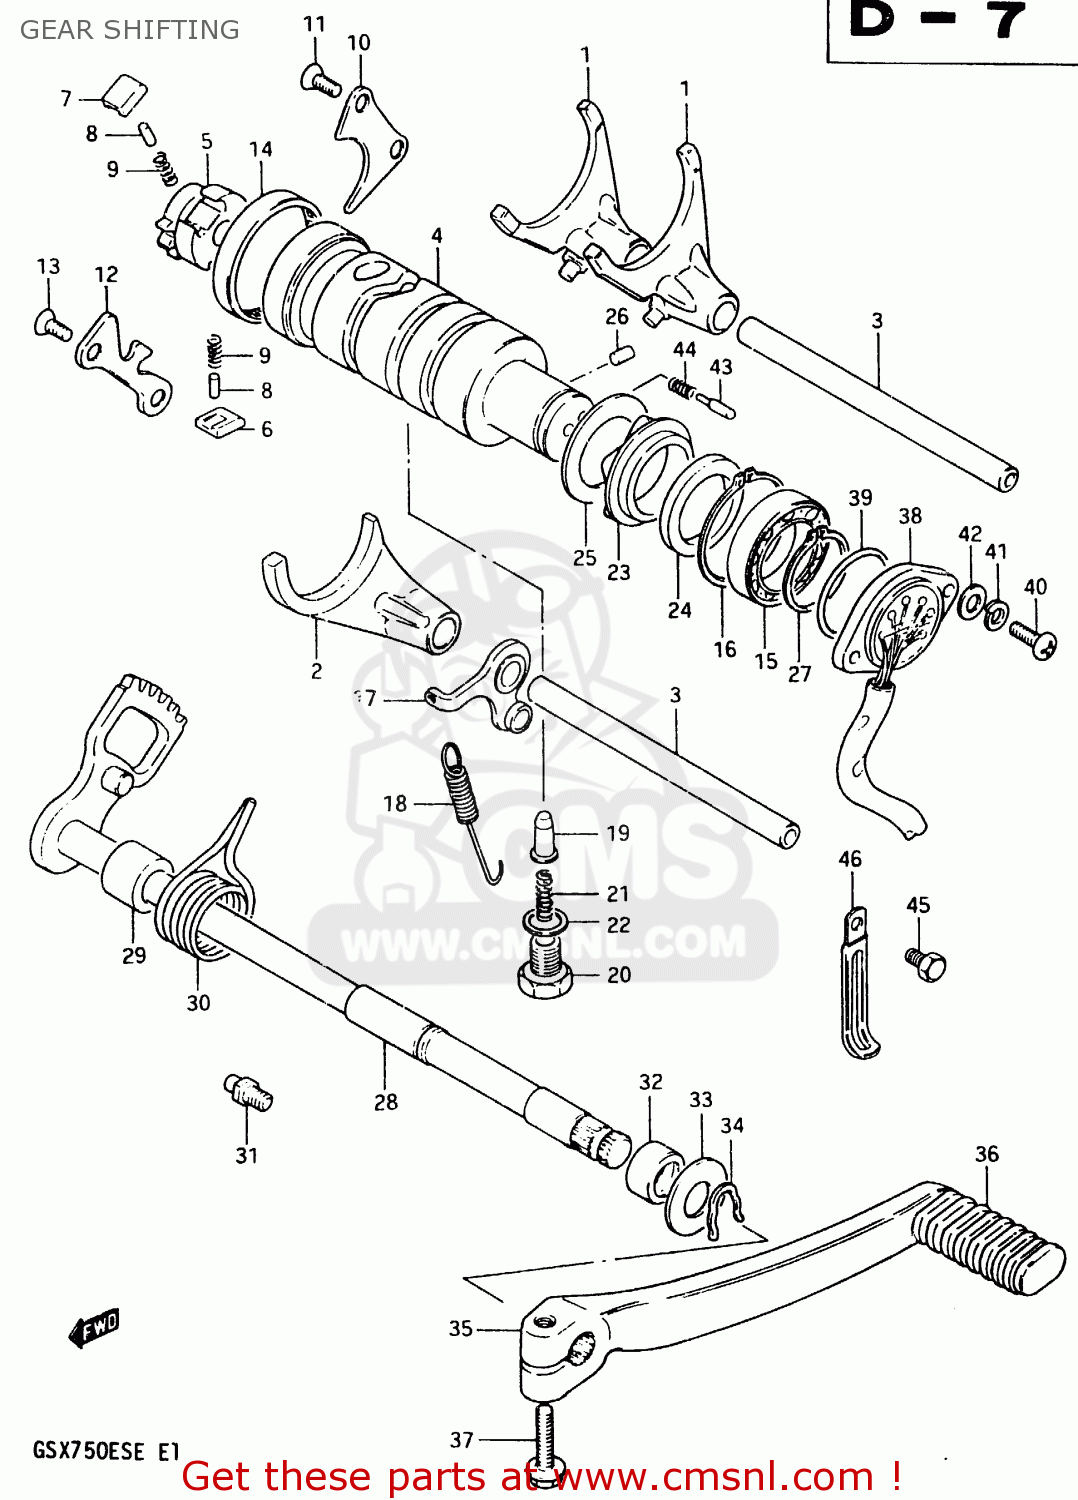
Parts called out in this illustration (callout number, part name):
1	FORK,GEAR SHIFT NO.1
2	FORK,GEAR SHIFT NO.2
3	SHAFT,GEAR SHIFT FORK
4	CAM,GEAR SHIFT
5	RETAINER,GEAR SHIFT CAM
6	PAWL,GEAR SHIFT NO.1
7	PAWL,GEAR SHIFT NO.2
8	PIN(5X8)
9	SPRING
10	LIFTER,GEAR SHIFT PAWL
11	SCREW
12	GUIDE,GEAR SHIFT CAM
13	SCREW
14	BEARING(43X49X12)
15	BALL BEARING
16	CIRCLIP,42MM
17	STOPPER,GEAR SHIFTING
18	SPRING
19	STOPPER,GEAR SHIFTING
20	HOLDER,GEAR SHIFT CAM STOP SPR
21	SPRING
22	GASKET(14X19.2X2) (NAS)
23	PLATE,STOPPER
24	WASHER
25	WASHER,LOCK
26	PIN 4X6
27	CIRCLIP,25MM
28	SHAFT,GEAR SHIFT
29	SPACER(12X20X15.3)
30	SPRING
31	STOPPER,GEAR SHIFT CAM
32	OIL SEAL
33	WASHER (12.5X27X1.6)
34	SPRING,RETAINER
35	LEVER ASSEMBLY,GEAR SHIFTING
36	RUBBER,PEDAL
37	BOLT
38	TERMINAL BASE,NEUTRAL
39	O RING(D:2.4,ID:36.5)
40	SCREW(5X14)
41	LOCK WASHER
42	WASHER
43	PIN(5X15.5)
44	SPRING
45	BOLT
46	CLAMP
